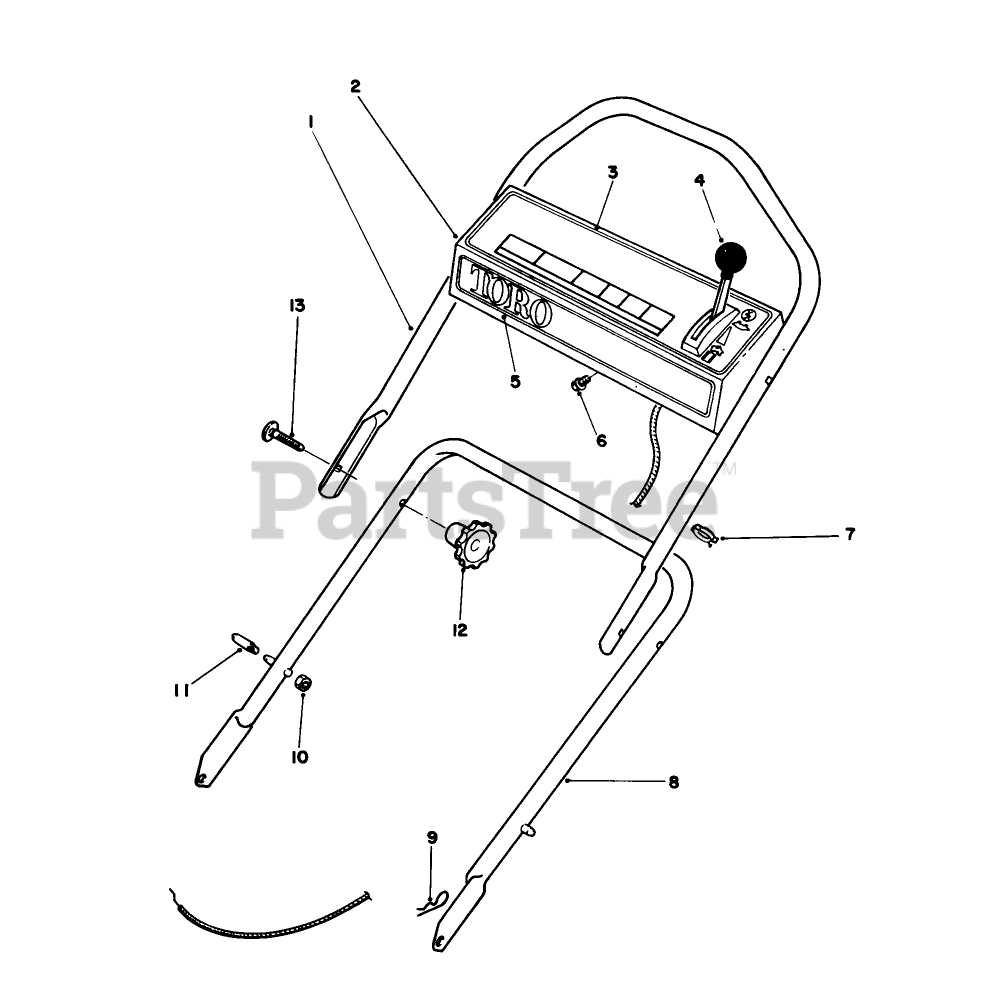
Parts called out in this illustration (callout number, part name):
4	THROTTLE CONT-SERVICE
6	SCREW-HWHTF
8	LOWER HANDLE ASM
9	PIN-COTTER, HAIR
10	NUT-LOCK, NI
11	HANDLE PIN
